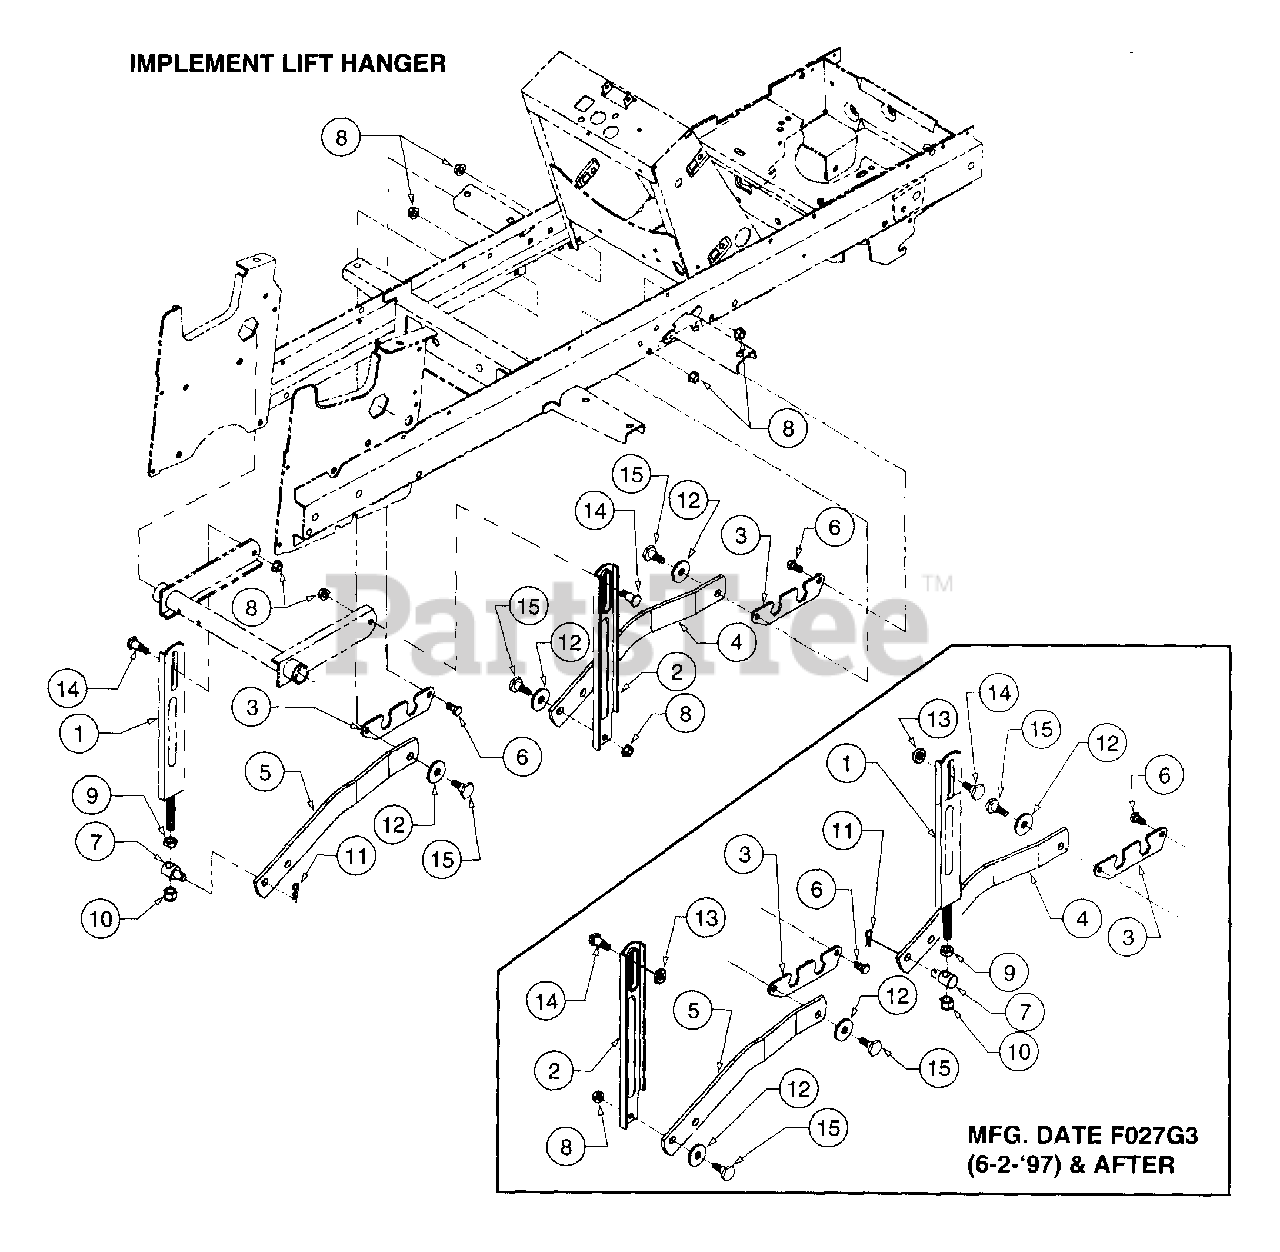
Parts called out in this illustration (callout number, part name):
7	Ferrule, Adjustment
8	Nut, Hex Flange Lock, 3/-16
9	Nut, Hex Jam, 1/2-13 GR5
10	Nut, Hex Insert Lock, 1/2-13
11	Pin, Internal Cotter
12	Washer, Flat, .50 x 1.5 x .15 Mfg.
13	Washer, Flat, .531 x .875 x .15 Mfg.
14	Bolt, Shoulder
15	Bolt, Shoulder
